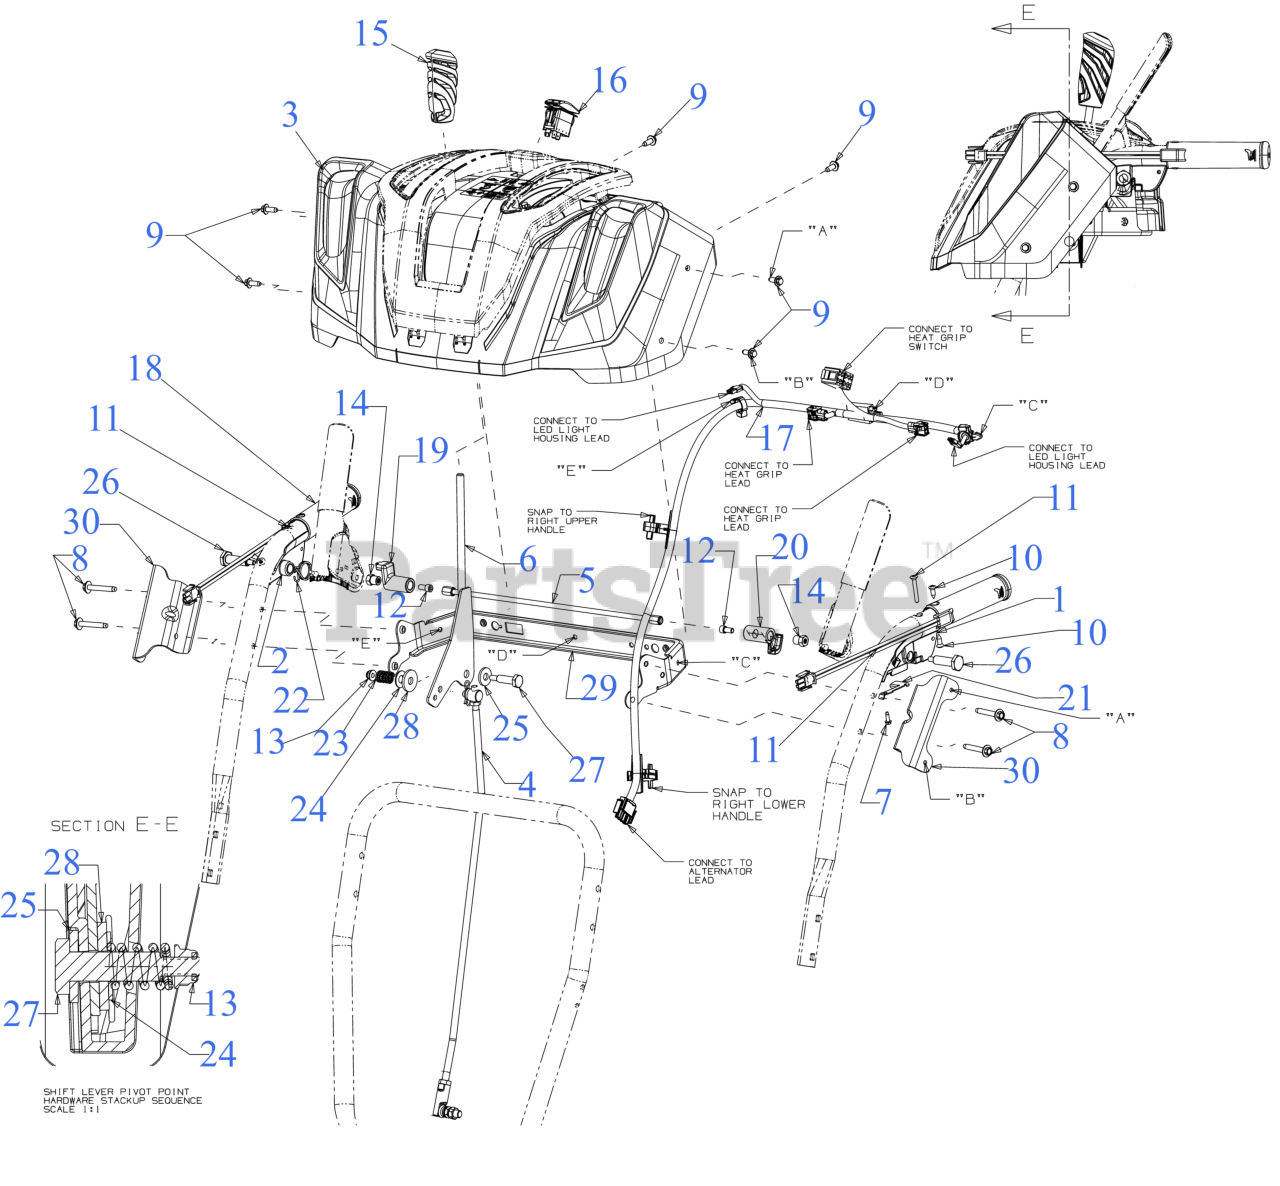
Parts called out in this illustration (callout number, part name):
1	CLUTCH LOCK HANDLE ASSEMBLY (LH)
2	CLUTCH LOCK HANDLE ASSEMBLY (RH)
3	HANDLE PANEL ASSEMBLY
4	Not Serviceable/ Components Only
7	SCREW #8-16 x .50
8	SCREW 1/4-20 x 1.625
9	SCREW M6-1 x .625
10	SCREW-AB #12-24 x .625
11	SCREW #10-24 x 1.375
12	SCREW 1/4-20 x .50
13	FLANGE LOCK NUT
14	HEX NUT W/PATCH
15	PTO HANDLE GRIP .355 ID
16	HEATED GRIP SWITCH
17	HARNESS (TWO HEADLIGHT)
18	HEATED GRIP
20	CLUTCH LOCK CAM
21	CLUTCH SPRING
22	TORSION SPRING
23	COMPRESSION SPRING
24	FLAT WASHER .401X.88
26	SHOULDER SCREW .437 x 1.345 1/4-20
27	SHOULDER SCREW
28	FRICTION WASHER
